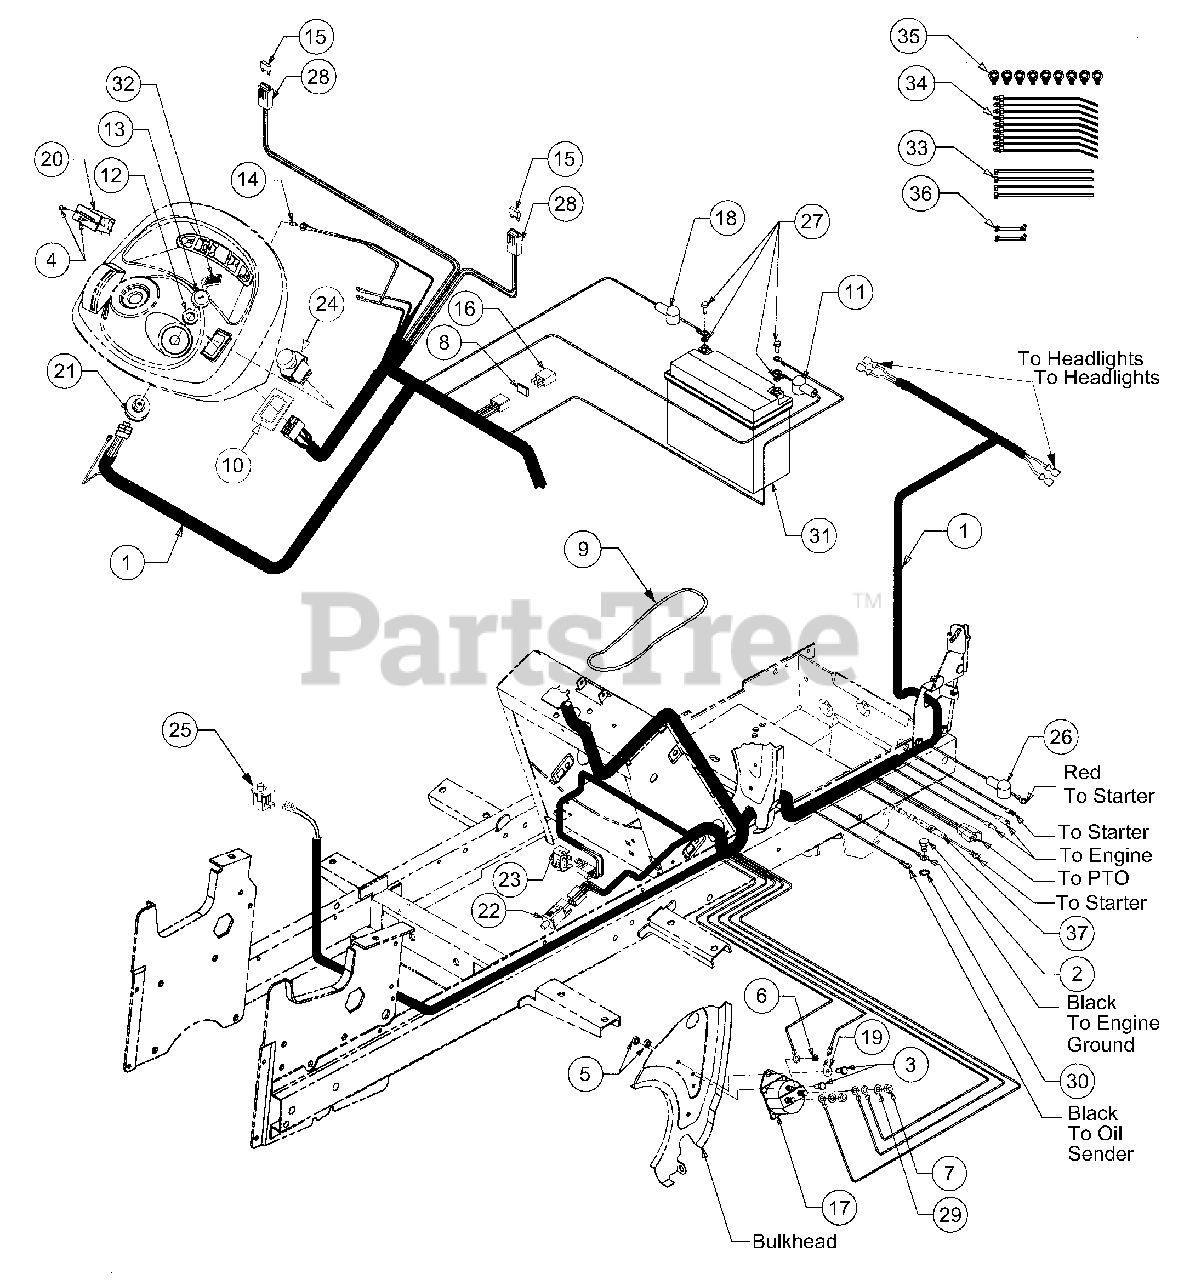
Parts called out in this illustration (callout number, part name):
1	Wire Harness, Main
2	Screw, Hex Cap, 3/8-16 x .50
3	Screw, Hex Cap, 1/4-20 x .625
4	Screw, Truss Hd Tapp, #6 x .62
5	Nut, Hex Sems, 1/4-20
6	Nut, Hex, #10-32
7	Nut, Hex, 5/16-18 GR5
8	Gasket, Silicone
9	Strap, Battery Retainer
10	Bracket, PTO Switch Retainer
11	Cover, Terminal Black
12	Nut, Ignition Switch
13	Cap, Ignition Switch
14	Bulb, Indicator
15	Fuse, 25 Amp
16	Relay
17	Solenoid, Starter
18	Cover, Terminal Red
19	Lug, Quick Connect
20	Hour Meter
21	Switch, Ignition
22	Switch, Interlock (Brake)
23	Switch, Snap Mount - Normally Closed
24	Switch, PTO
25	Switch, Seat
26	Cover, Terminal Red
27	Battery Cable Hardware
28	Holder, Fuse w/Mounting Clip
29	Washer, Lock, 5/16
30	Washer, External Lock, 3/8
31	Battery
32	Key, Ignition (Set of 2)
33	Tie, Self-Clinch Cable
34	Tie, Pushmount
35	Clip, Cable
36	Clip, Cable
37	Diode Assembly w/Lead
